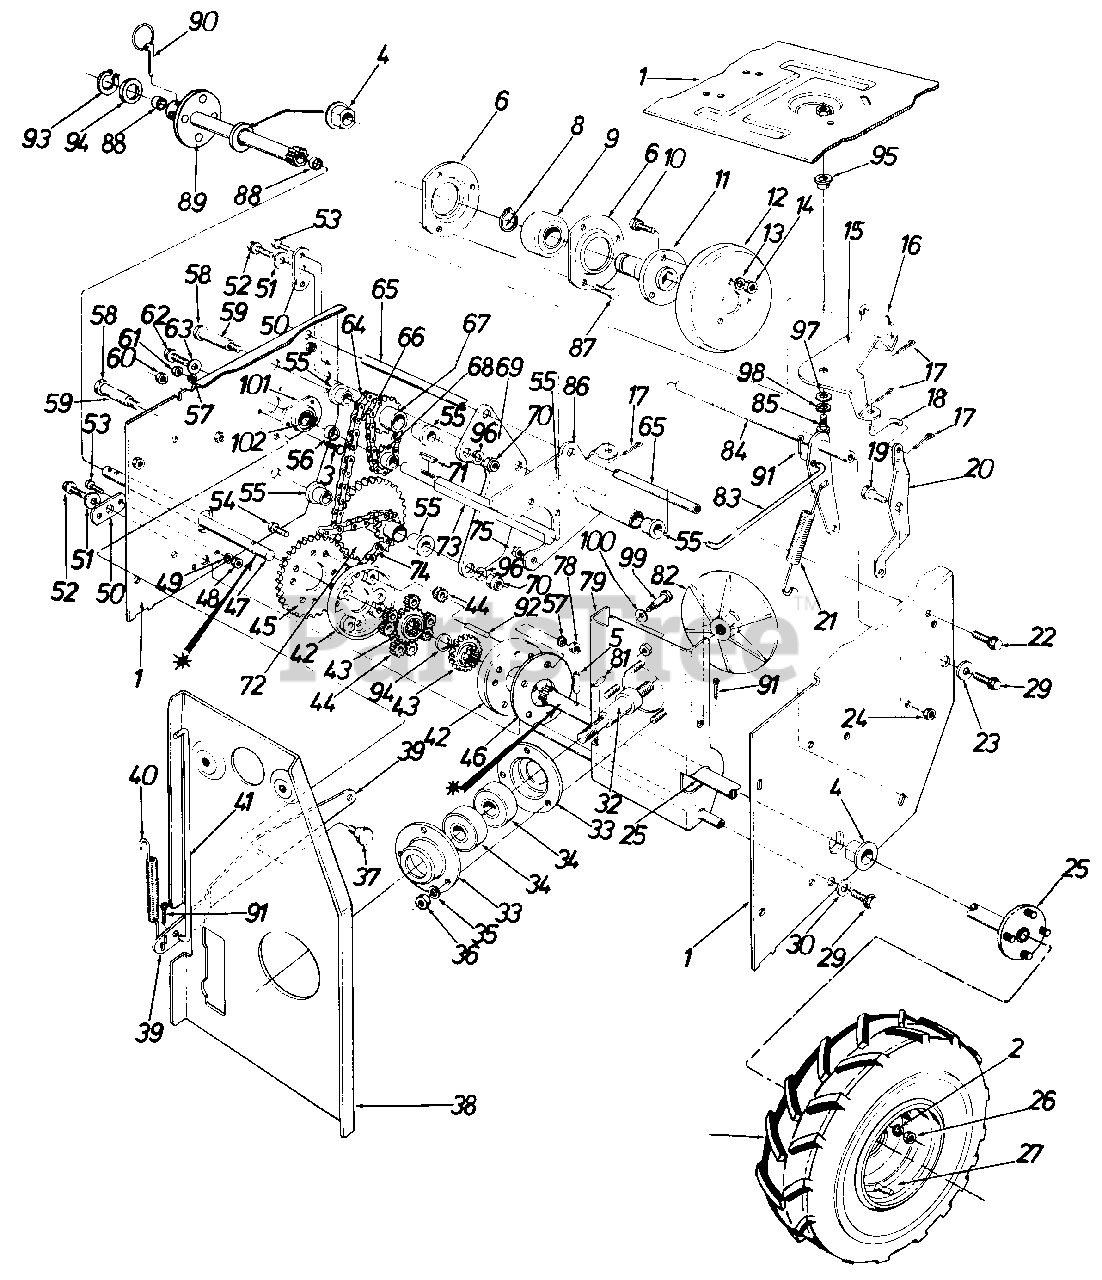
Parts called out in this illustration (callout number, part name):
1	Frame Ass'y.
2	L-Wash. 3/8" Scr.
3	Hex Bolt 1/4-20 x .62" Lg.
4	Flange Brg. w/Flats 1.00" I.D.
5	H-Spring Pin Spiral 3/16" Dia. x 1.25" Lg.
6	Bearing Housing
8	Snap Ring for 1.00" Dia. Shaft
9	Ball Brg. 25 mm x 52 mm x 15 mm Thk.
10	Hex Sems Scr. 5/16-18 x .75" Lg.
11	Friction Wheel Adapter
12	Friction Wheel Ass'y.
13	L-Wash. 5/16" Scr.
14	Hex Nut 5/16-18" Thd.
15	Sliding Linkage Brkt.
16	Brake Rod - .31" Dia. x 2.00" Lg.
17	Cot. Pin 3/32" Dia. x .75" Lg.
18	Shifting Linkage Rod .31" Dia. x 2.25" Lg.
19	Shld. Scr. .625" Dia. x .170" Lg.
20	Shifting Linkage Brkt.
21	Extension Spring .73 O.D. x 4.31" Lg.
22	Hex L-Scr. 5/16-18 x .62" Lg.
23	Fl-Wash. .345 I.D. x .75 O.D. x .060
24	Hex Cent. L-Nut 3/8-16 Thd.
25	Differential Shaft Ass'y. - L.H.
26	Hex Nut 3/8-16 Thd.
27	Wheel Rim Ass'y.
29	Hex L-Scr. 5/16-18 x .62" Lg.
30	Fl-Wash. .345" I.D. x .75 O.D. x .060
32	Drive Plate Spindle
33	Bearing Housing
34	Ball Brg. .787 I.D. x 1.85 O.D. x .56
35	L-Wash. 5/16" Scr.
36	Hex Nut 5/16-18 Thd.
37	Shld. Scr. .625" Dia. x .170" Lg.
38	Engine Brkt. Ass'y.
39	Auger Clutch Brkt.
40	Extension Spring .38 O.D. x 3.18" Lg.
41	Auger Clutch Rod .31" Dia. x 10.62" Lg.
42	Differential Housing
43	20 Tooth Spur Gear
44	9 Tooth Spur Gear
45	28 Tooth Sprocket
46	Differential Hsg. Support Plate
47	Differential Connecting Shaft
48	Hex Nut 1/4-20 Thd.
49	L-Wash. 1/4" Scr.
50	Pivot Axle Brkt.
51	Fl-Wash. .345" I.D. x .88" O.D. x .060
52	Hex L-Scr. 5/16-18 x .62" Lg.
53	Hex Scr. 1/4-20 x .62" Lg.
54	Hex Scr. 1/4-28 x 1.75" Lg.
55	Flange Brg. - .630" I.D.
56	Spacer .51" I.D. x .69" O.D. x .44
57	L-Wash. 1/4" Scr.
58	Hex Scr. 3/8-24 x 2.75" Lg.
59	Sprocket Hub Tubing 1.900" Lg.
60	Hex Cent. L-Nut 3/8-16 Thd.
61	Hex Nut 1/4-20 Thd.
62	Hex L-Scr. 5/16-18 x .62" Lg.
63	Bell-Wash. .345" I.D. x .88 O.D. x .060
64	#41 Chain - 1/2" Pitch x 43 Links
65	Sliding Support Axle
66	#41 Chain 1/2" Pitch x 19 Links
67	9 and 14 Teeth Sprocket Hub Ass'y.
68	8 Teeth Sprocket
71	#9 Hi-Pro Key 3/32 x 5/8" Dia.
72	9 and 32 Teeth Sprocket Hub Ass'y.
73	Hex Shaft
74	#420 Chain - 1/2" Pitch x 37 Links
75	Hex Ins. Jam L-Nut 1/4-28"
78	Hex Nut 1/4-28 Thd.
82	Aluminum Drive Plate
83	Drive Clutch Rod .31" Dia. x 7.38" Lg.
84	Drive Clutch Brkt. Ass'y.
85	Hex Scr. 3/8-16 x 1.00" Lg.
86	Sliding Brkt. Ass'y.
87	Hex Scr. 1/4-28 x .62" Lg.
88	Sleeve Brg. .630 I.D.
89	Differential Tubing Ass'y. - R.H.
90	Klick Pin 1/4" Dia. x 1.75" Lg.
91	Internal Cot. Pin 5/16 Dia.
92	Differential Pin
93	Snap Ring .625 Shaft
94	Fl-Wash. .62 I.D. x 1.25 O.D. x .060
95	Shld. Spacer 5/8" I.D.
96	L-Wash. 3/8" Scr.
97	Fl-Wash.
98	L-Wash. 3/8" Scr.
99	Shld. Scr.
100	Bell-Wash.
101	Bearing Housing
102	Ball Bearing
